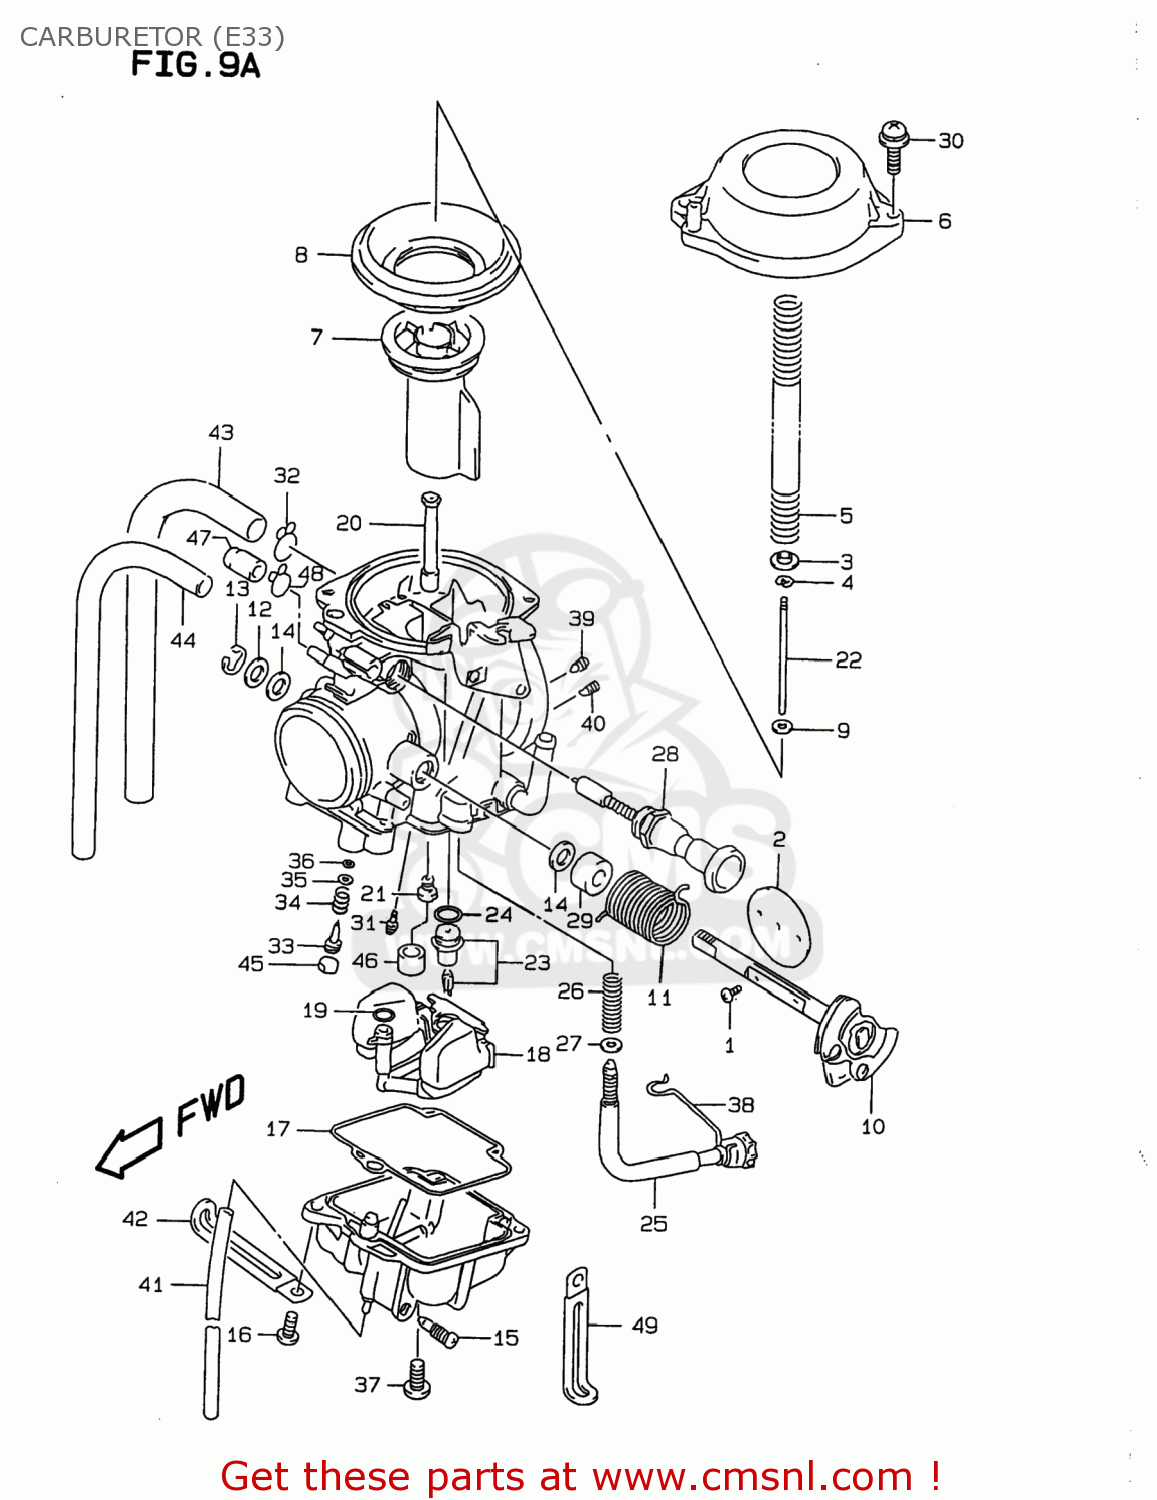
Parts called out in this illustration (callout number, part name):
1	SCREW
2	VALVE,THROTTLE (115)
3	RING
4	E RING
5	SPRING
6	COVER,DIAPHRAGM
7	VALVE PISTON
8	DIAPHRAGM
9	RING
10	SHAFT ASSEMBLY
11	SPRING
12	GASKET,THROTTLE SHAFT (NAS)
13	E RING
14	SEAL
15	SCREW,DRAIN
16	SCREW
17	GASKET,FLOAT CHAMBER (NAS)
18	FLOAT ASSY
19	O RING
20	JET,NEEDLE(P-1M)
21	JET,MAIN(122.5)
22	NEEDLE,JET
23	VALVE ASSY,NEEDLE
24	O-RING,NEEDLE VALVE
25	ADJUSTER
26	SPRING,THROTTLE SCREW
27	WASHER,STARTER SHAFT
28	PLUNGER ASSEMBLY
29	RING
30	SCREW
31	JET,PILOT(35)
32	CLIP
33	SCREW,PILOT
34	SPRING
35	WASHER
36	O RING,PILOT AIR SCREW
37	SCREW
38	CLIP
39	JET,AIR(1.2)
40	JET,AIR(0.6)
41	HOSE(3X5X600)
42	CLAMP
43	HOSE(7X11X600)
44	HOSE(4.5X8.5X600)
45	PLUG
46	RING
47	CAP
48	CLIP
49	CLAMP(L:45)
